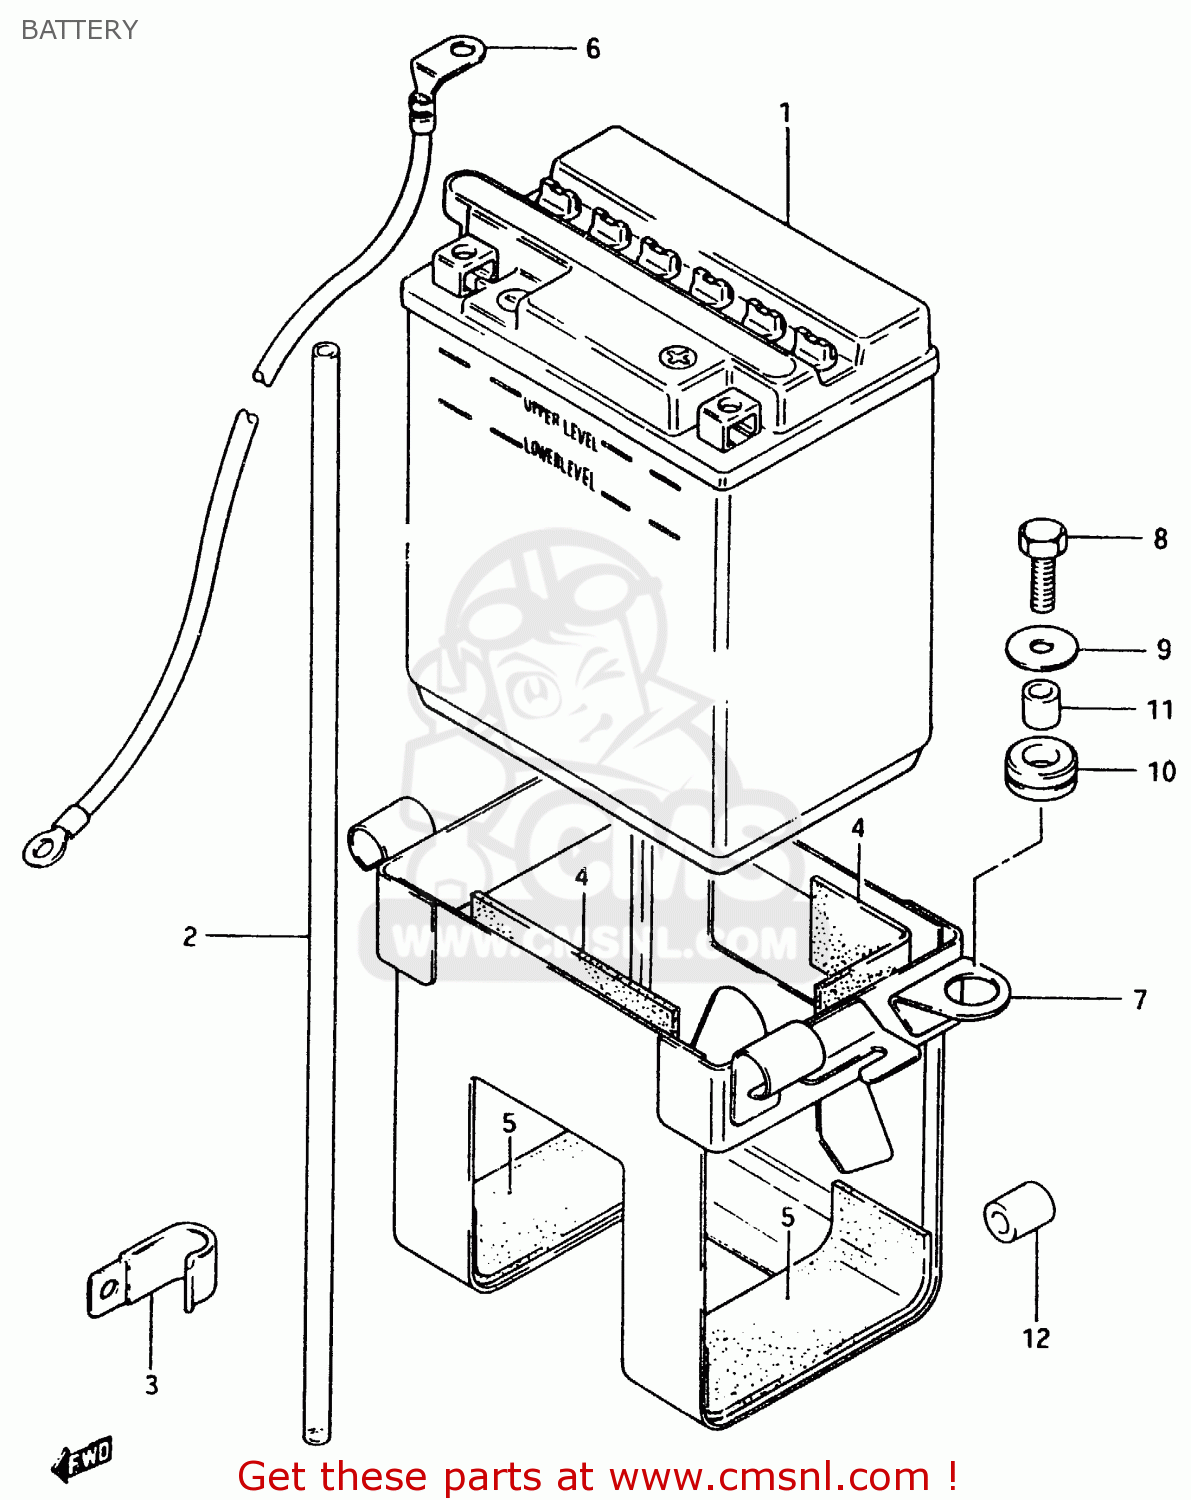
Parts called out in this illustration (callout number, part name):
1	BATTERY ASSY (12V)
2	HOSE,BATTERY EXHAUST
3	CLAMP
4	PROTECTOR(30X80X2)
5	PROTECTOR(170X95X3.0)
6	WIRE,STARTER MOTOR LEAD
7	HOLDER,BATTERY
8	SCREW
9	WASHER (6.5X20X1.2)
10	CUSHION
11	SPACER(6.1X9X7.5)
12	CUSHION
